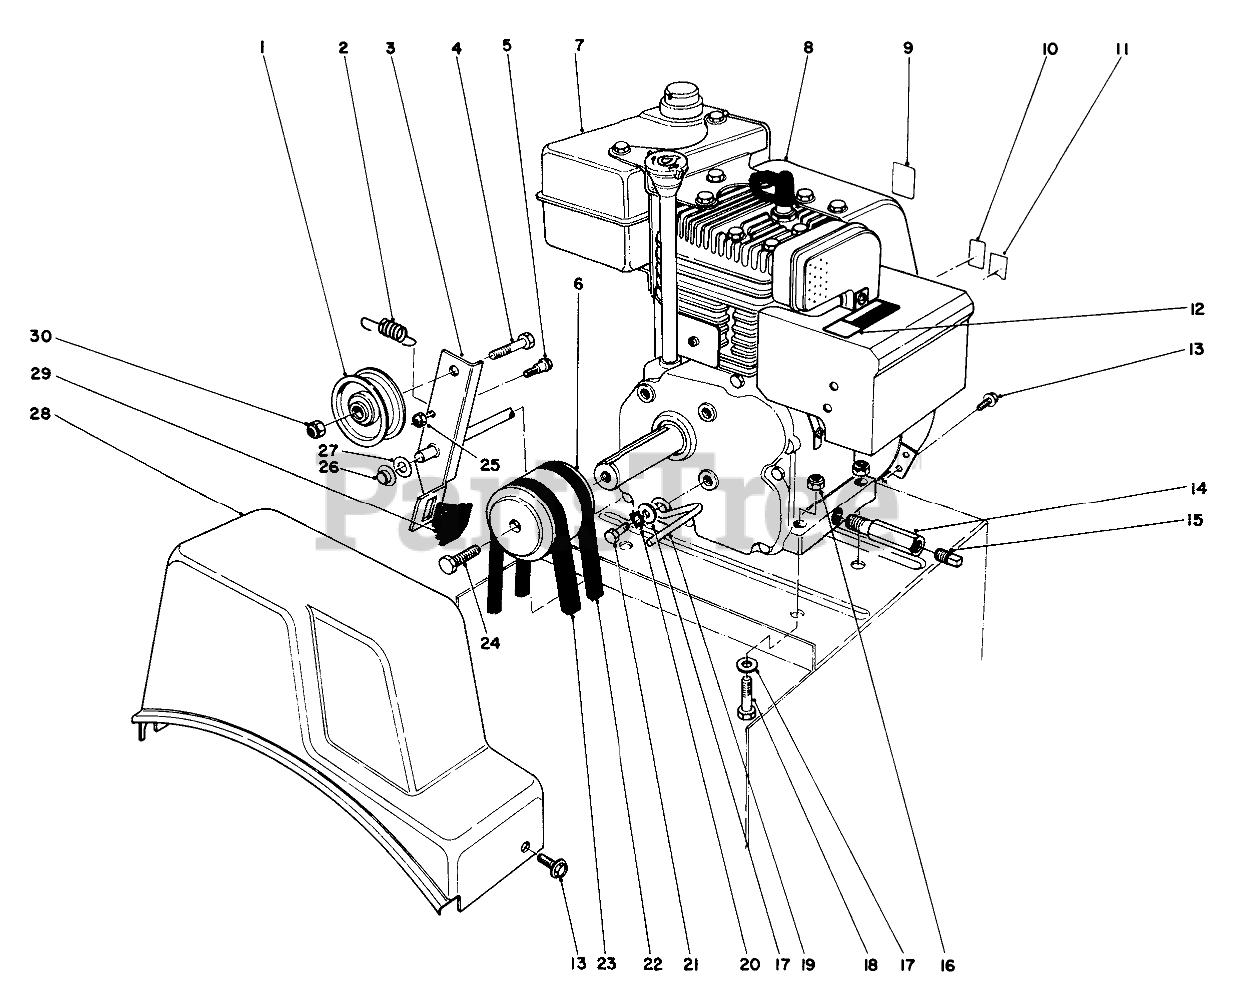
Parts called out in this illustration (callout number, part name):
1	PULLEY-IDLER
2	SPRING
3	Auger Clutch (Incl. Ref. #29)
4	SCREW-HH
5	BOLT-SHOULDER
6	PULLEY-ENGINE
7	GAS TANK 2 QT W CAP
9	DECAL-PRIMER
10	THROTTLE DECAL, INT'L
11	CHOKE DECAL
11	DECAL-CHOKE
12	Decal-Hot
12	DECAL-HOT SURFACE, WARNING
13	SCREW-HWH
14	PIPE-NIPPLE
15	CAP-PIPE
16	NUT-LOCK, NI
17	WASHER-PLAIN
18	SCREW-HH
19	RETAINER-BELT
20	WASHER-LOCK
21	SCREW-HH
22	V BELT-3L, TRACTION
23	V-BELT (29.50 INCH)
24	SCREW-SPECIAL
25	NUT-LOCK, NI
26	RETAINER-PUSH ON
27	WASHER-FLAT
28	COVER-BELT
29	PAD-BRAKE
30	NUT-LOCK, NI
